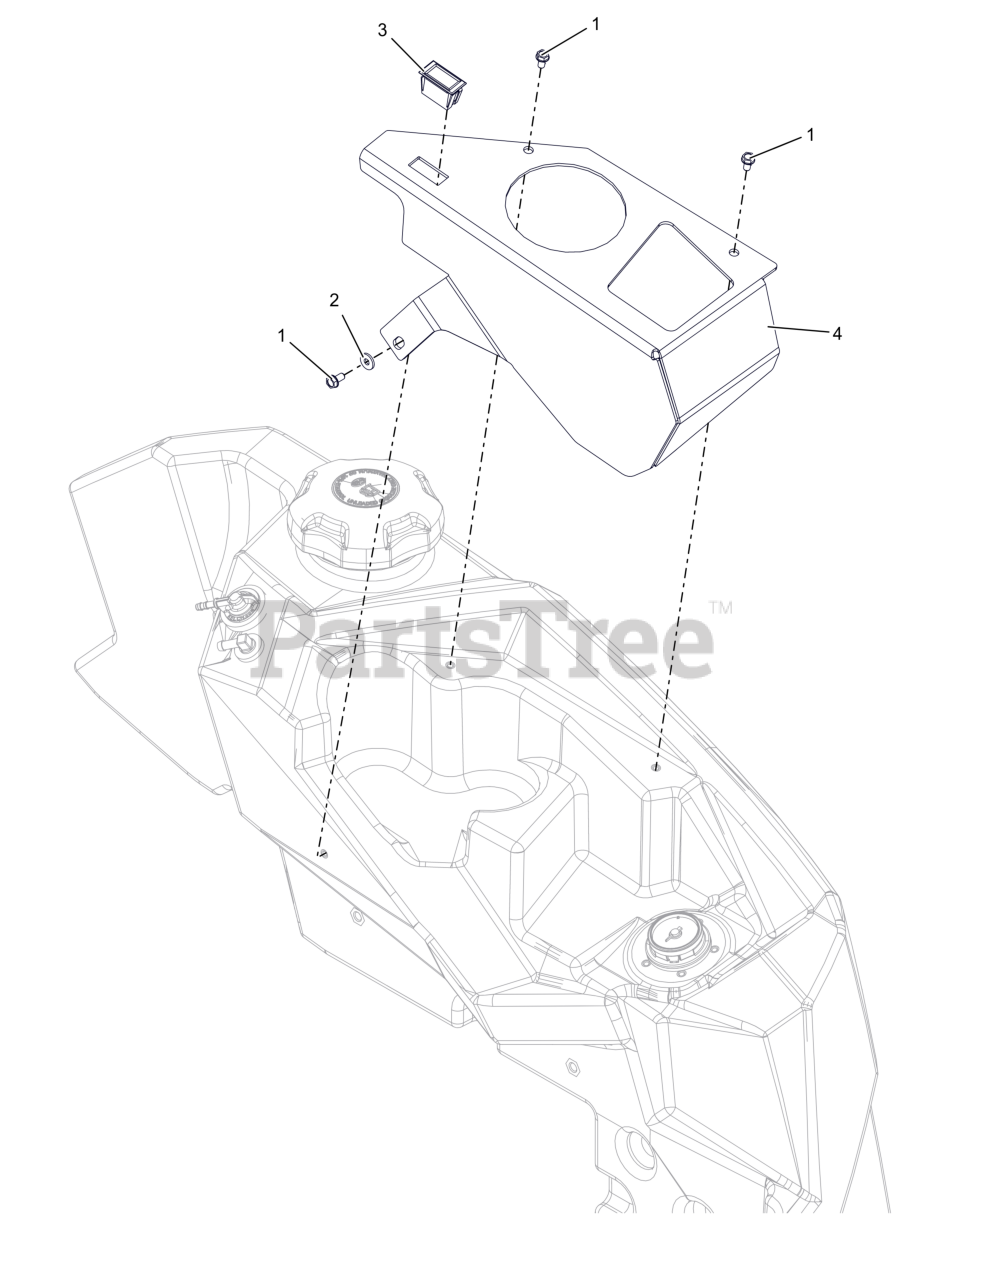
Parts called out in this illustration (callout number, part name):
1	SCR-MCH 10-24X.38 HWHSTAINLESS
2	WSHR-FL-STL .196X.50X.06 ZC120
3	SWITCH,BLANK
4	PANEL- LH CONTROL (RED)
